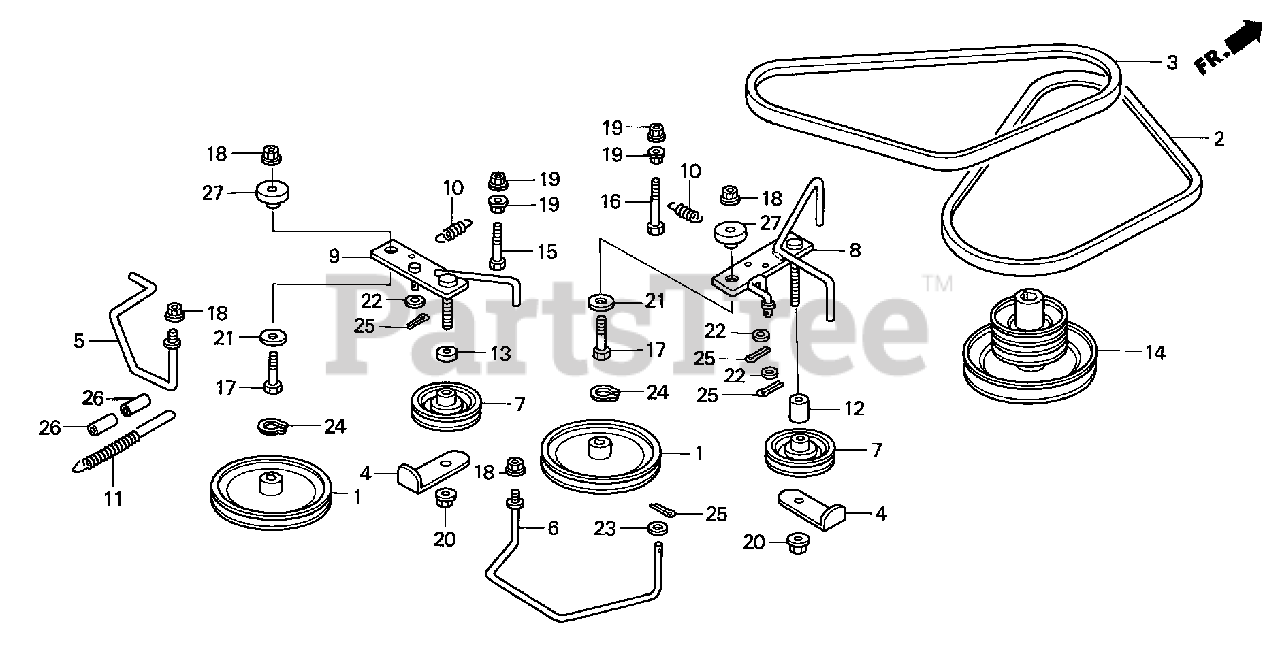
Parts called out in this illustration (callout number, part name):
1	PULLEY, TRANSMISSION
2	V-BELT, R. TRANSMISSION
3	V-BELT, L. TRANSMISSION
4	STOPPER C, BELT
5	STOPPER D, BELT
6	STOPPER E, BELT
7	ROLLER, TENSION
8	ARM, R. TENSIONER
9	ARM, L. TENSIONER
10	SPRING, TENSIONER RETURN
11	SPRING, BELT TENSIONER
12	SPACER, R. IDLER
13	SPACER, L. IDLER
14	PULLEY, ENGINE
15	BOLT, HEX. (1/4-20X1 1/4")
16	BOLT, HEX. (1/4-20X1 3/4")
17	BOLT, HEX. (5/16-18-1 1/4")
18	NUT, WHIZ-LOCK (1/4"-20)
19	NUT, WHIZ-LOCK (5/16"-18)
20	NUT, WHIZ-LOCK (3/8"-16)
21	WASHER, FLAT (5/16-1 1/8X0.063")
22	WASHER, FLAT (1/4")
23	WASHER, FLAT (5/16")
24	CIRCLIP, EX. (5/8")
25	PIN, COTTER (3/32" X 3/4")
26	COLLAR, DRIVE SPRING
27	COLLAR, TENSIONER ARM
